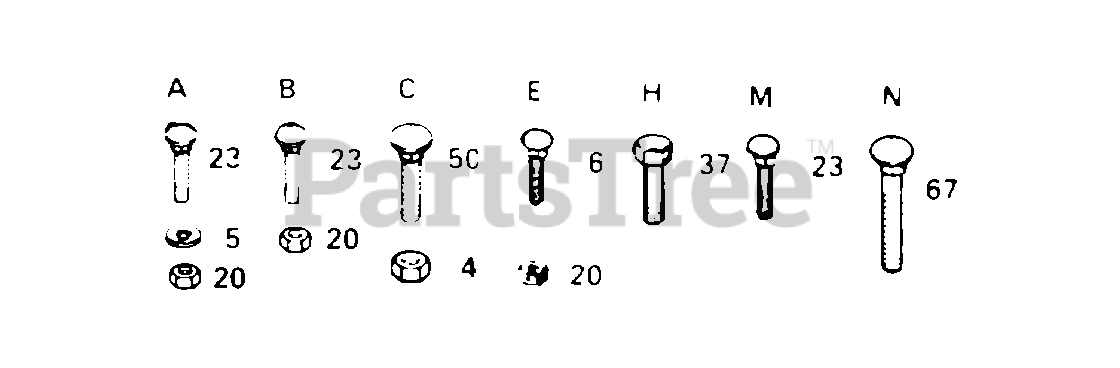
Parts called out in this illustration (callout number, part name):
5	WASHER M
6	BOLT
23	BOLT
37	SCREW
50	BOLT
67	BOLT.3/8-14X1.25
